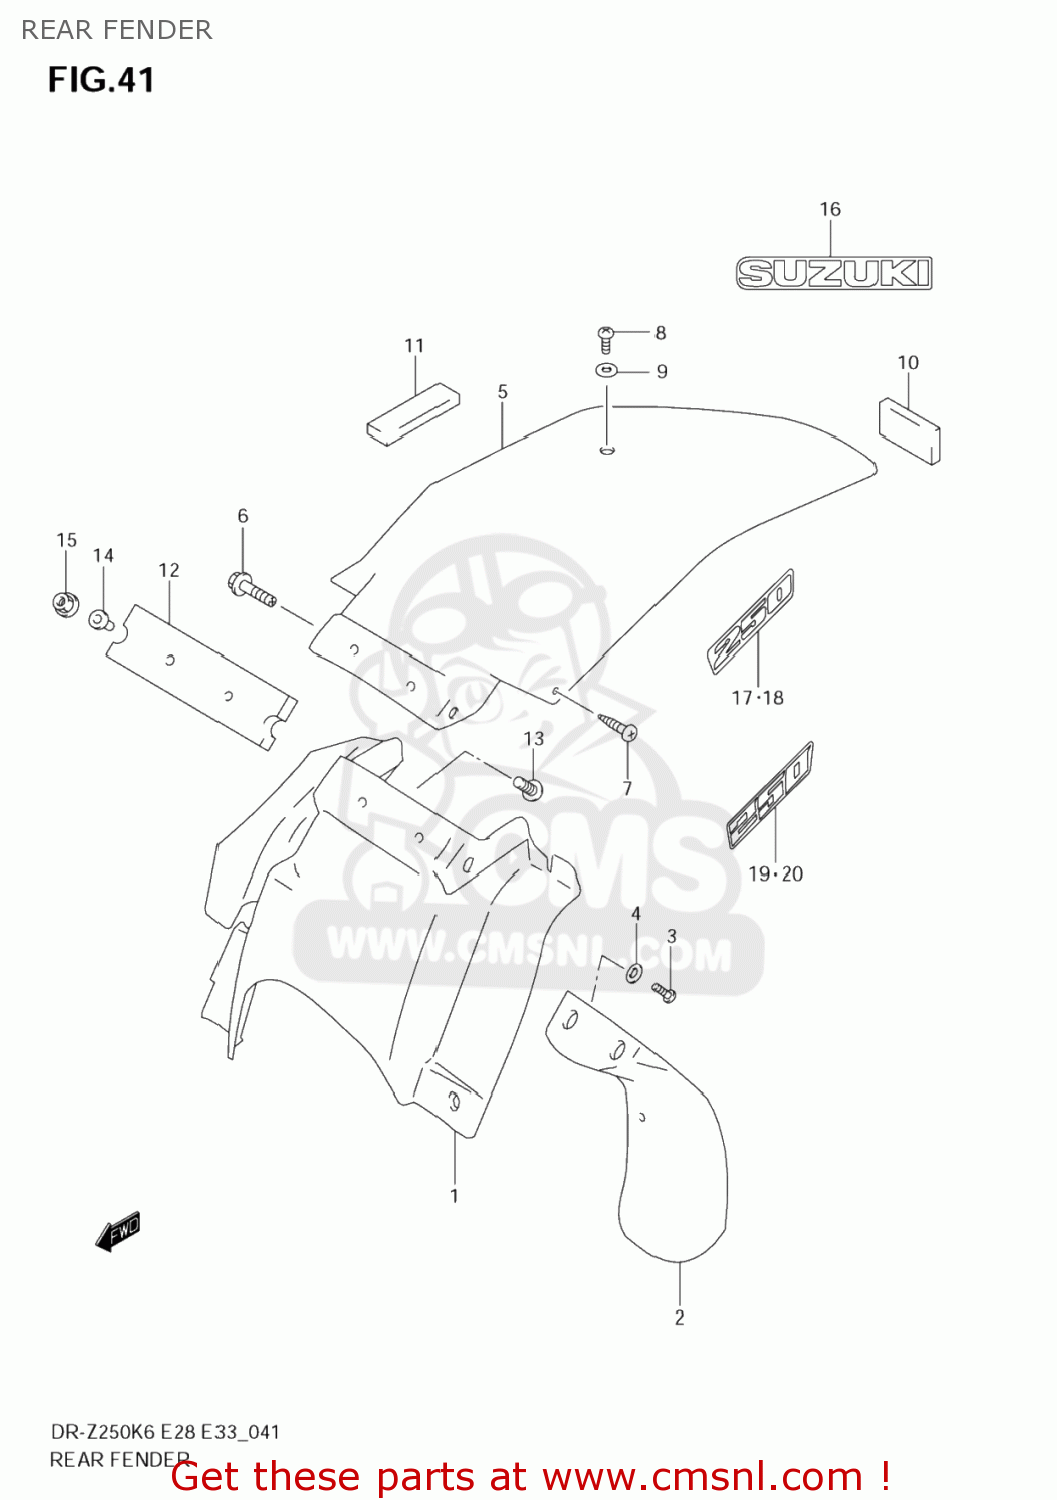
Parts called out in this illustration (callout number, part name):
1	BODY,RR FENDER FR
2	GUARD,RR FENDER MUD
3	SCREW 6X12
4	WASHER
5	BODY,RR FENDER RR
6	BOLT 6X12
7	SCREW(6X16)
8	SCREW,6X16
9	WASHER
10	CUSHION
11	PROTECTOR,RR FENDER
12	CUSHION,RR FENDER FR
13	SCREW 5X20
14	WASHER
15	NUT
16	EMBLEM,RR
17	EMBLEM,R
18	EMBLEM,L
19	EMBLEM,250,R
20	EMBLEM,250,L
